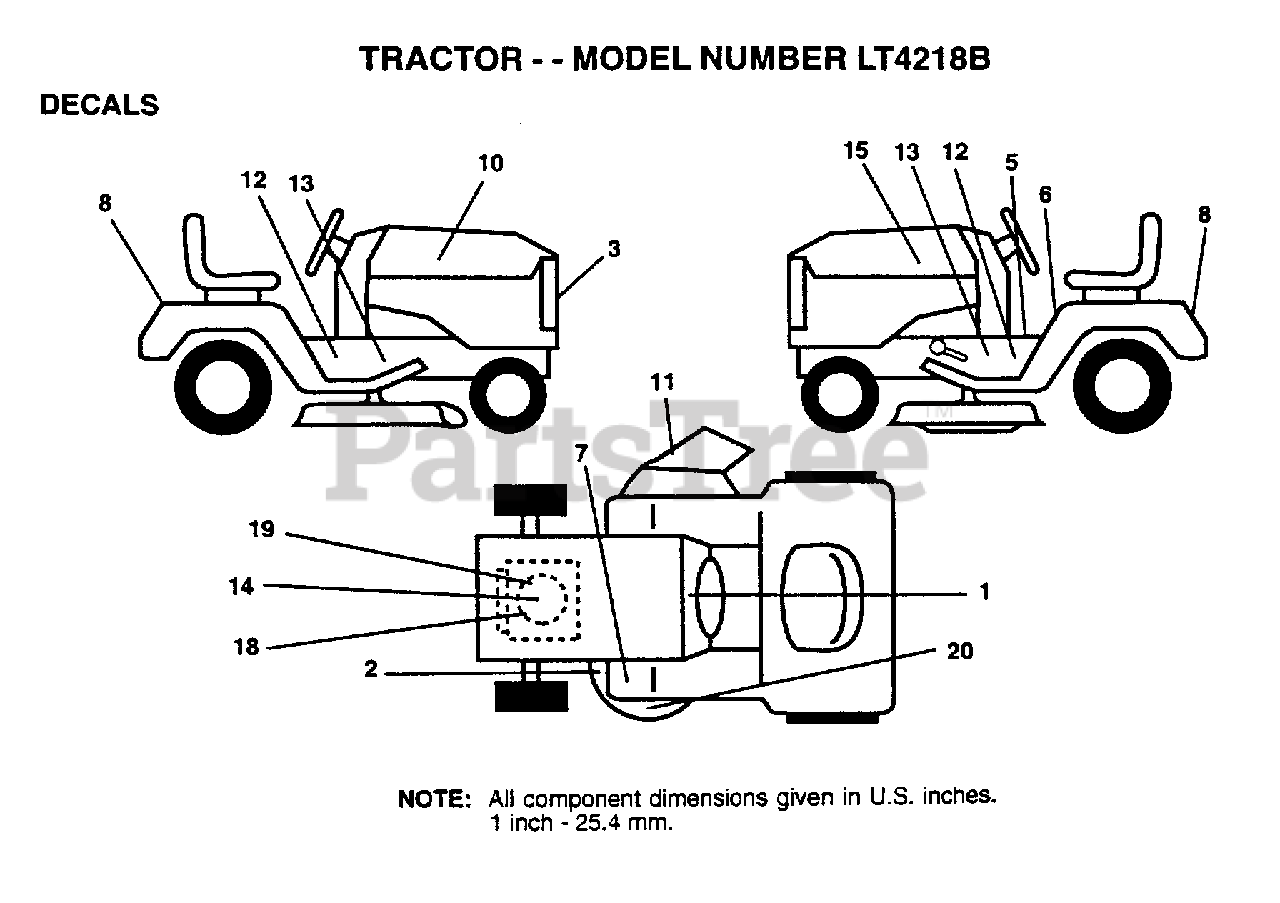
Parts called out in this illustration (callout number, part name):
1	DECAL INST OP DAS
2	DECAL
3	DECAL LOGO GRILLE
5	DECAL BRAK PARK
6	DECAL CAUT FEND
7	DECAL CLUT/BRAKE
8	DECAL FEND QUICK
10	DECAL HD RH
11	DECAL DANGER CT/F
12	DECAL CHASSIS KGR
14	DECAL.ENG.272757
15	DECAL HD LH
18	DECAL.ENG.272101
20	DECAL DECK MULCH
